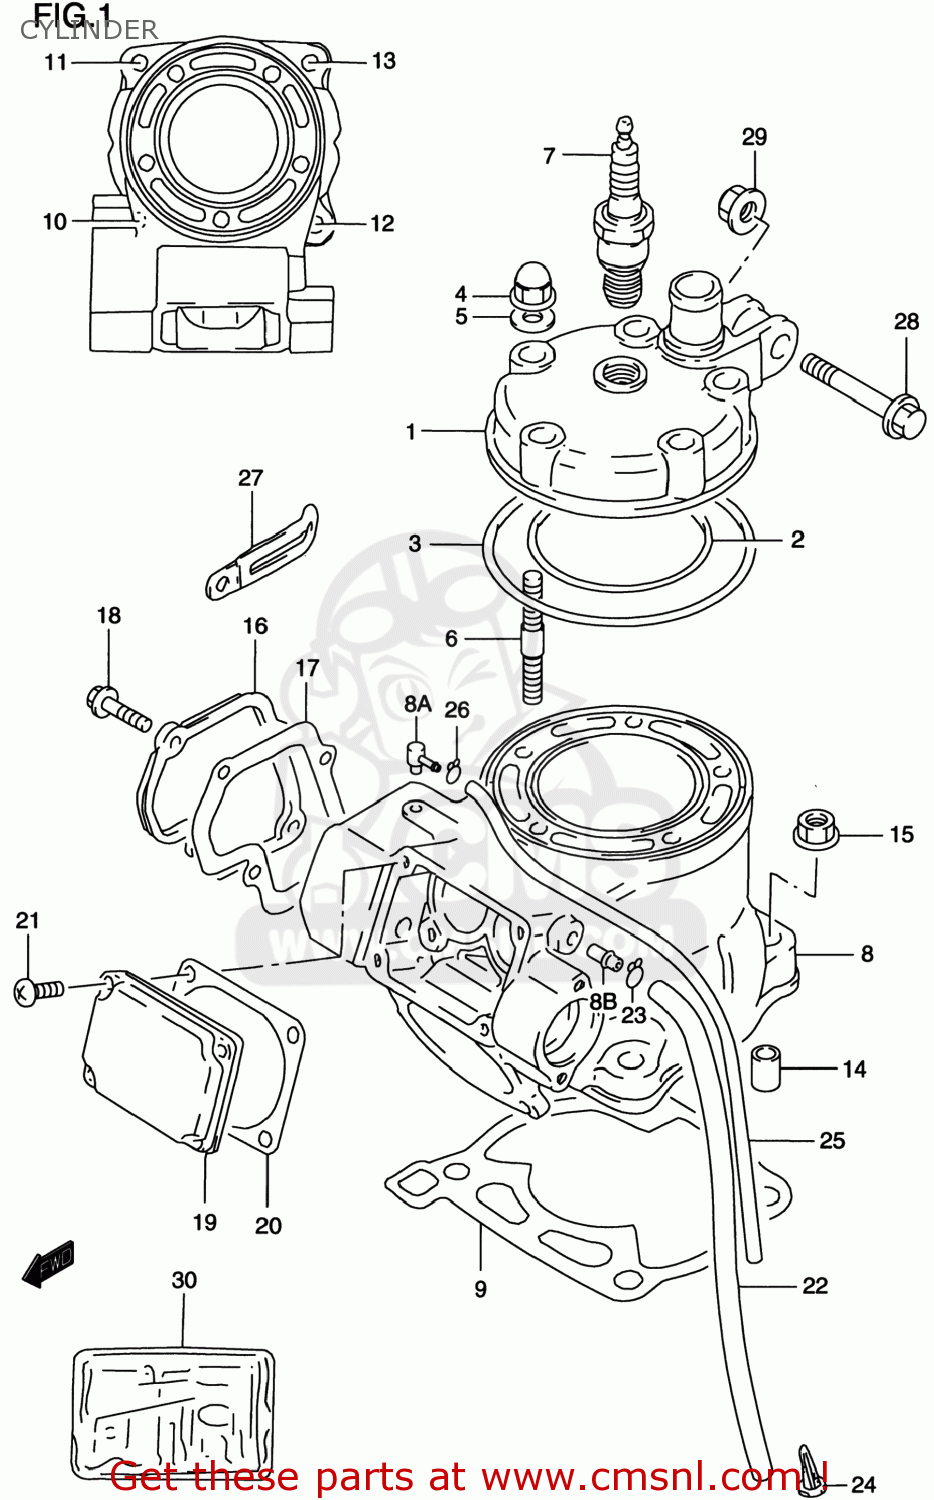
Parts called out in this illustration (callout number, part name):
1	HEAD,CYLINDER
2	O RING,CYLINDER HEAD NO.1
3	O RING,CYLINDER HEAD NO.2
4	NUT
5	GASKET(8.5X17X2.3) (NAS)
6	BOLT,STUD
7	PLUG,SPARK(R6918B-8)
8	CYLINDER SET
8A	UNION,BREATHER HOSE
8B	UNION
9	GASKET,CYLINDER (NAS)
10	STUD 8X25
11	BOLT,STUD
12	STUD BOLT
13	BOLT,STUD
14	PIN(8.4X11X14)
15	NUT
16	COVER,CYLINDER NO.1
17	GASKET,CYLINDER COVER NO.1 (NAS)
18	BOLT
19	COVER,CYLINDER NO.2
20	GASKET,CYLINDER COVER NO.2
21	BOLT
22	HOSE
23	CLIP
24	FILTER,EXH VALVE BREATHER HOSE
25	HOSE(5X8.2X600)
26	CLIP
27	CLAMP(L:45)
28	BOLT(8X41)
29	NUT
30	GASKET SET (NAS)
